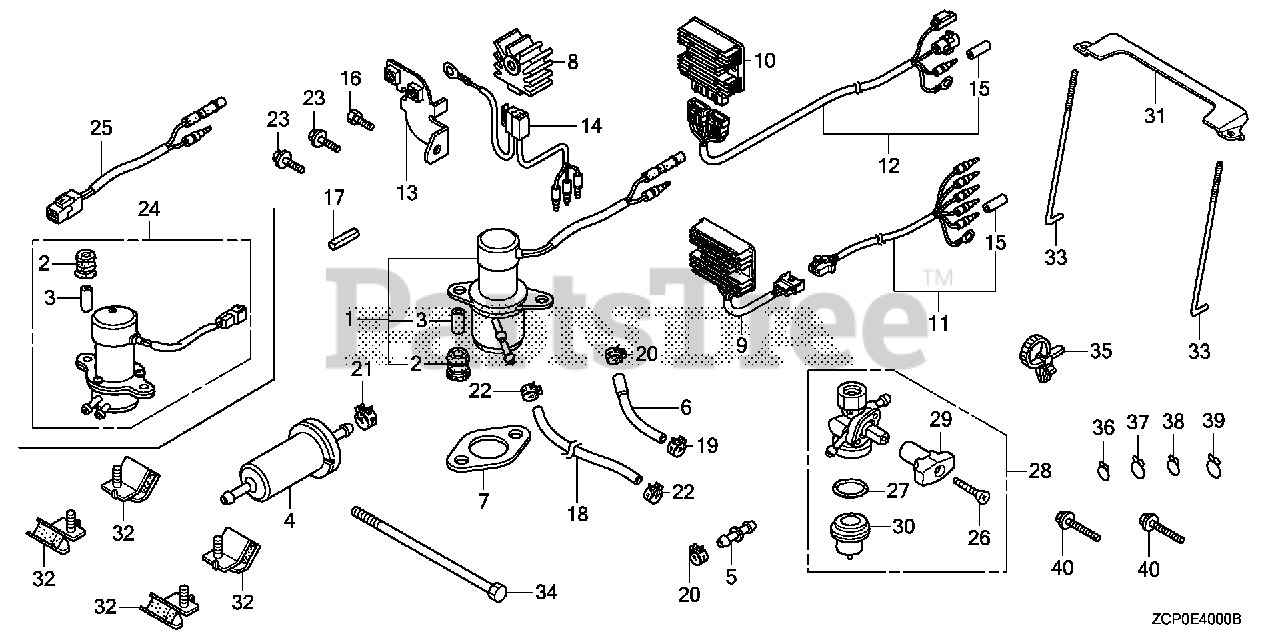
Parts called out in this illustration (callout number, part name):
7	GASKET, EX. PIPE
9	RECTIFIER ASSY., REGULATOR (20A)
11	SUB-WIRE HARNESS ASSY.
15	PLUG, CONNECTOR (OUTER) (ENGINE NO.)
23	BOLT, FLANGE (8X14)
